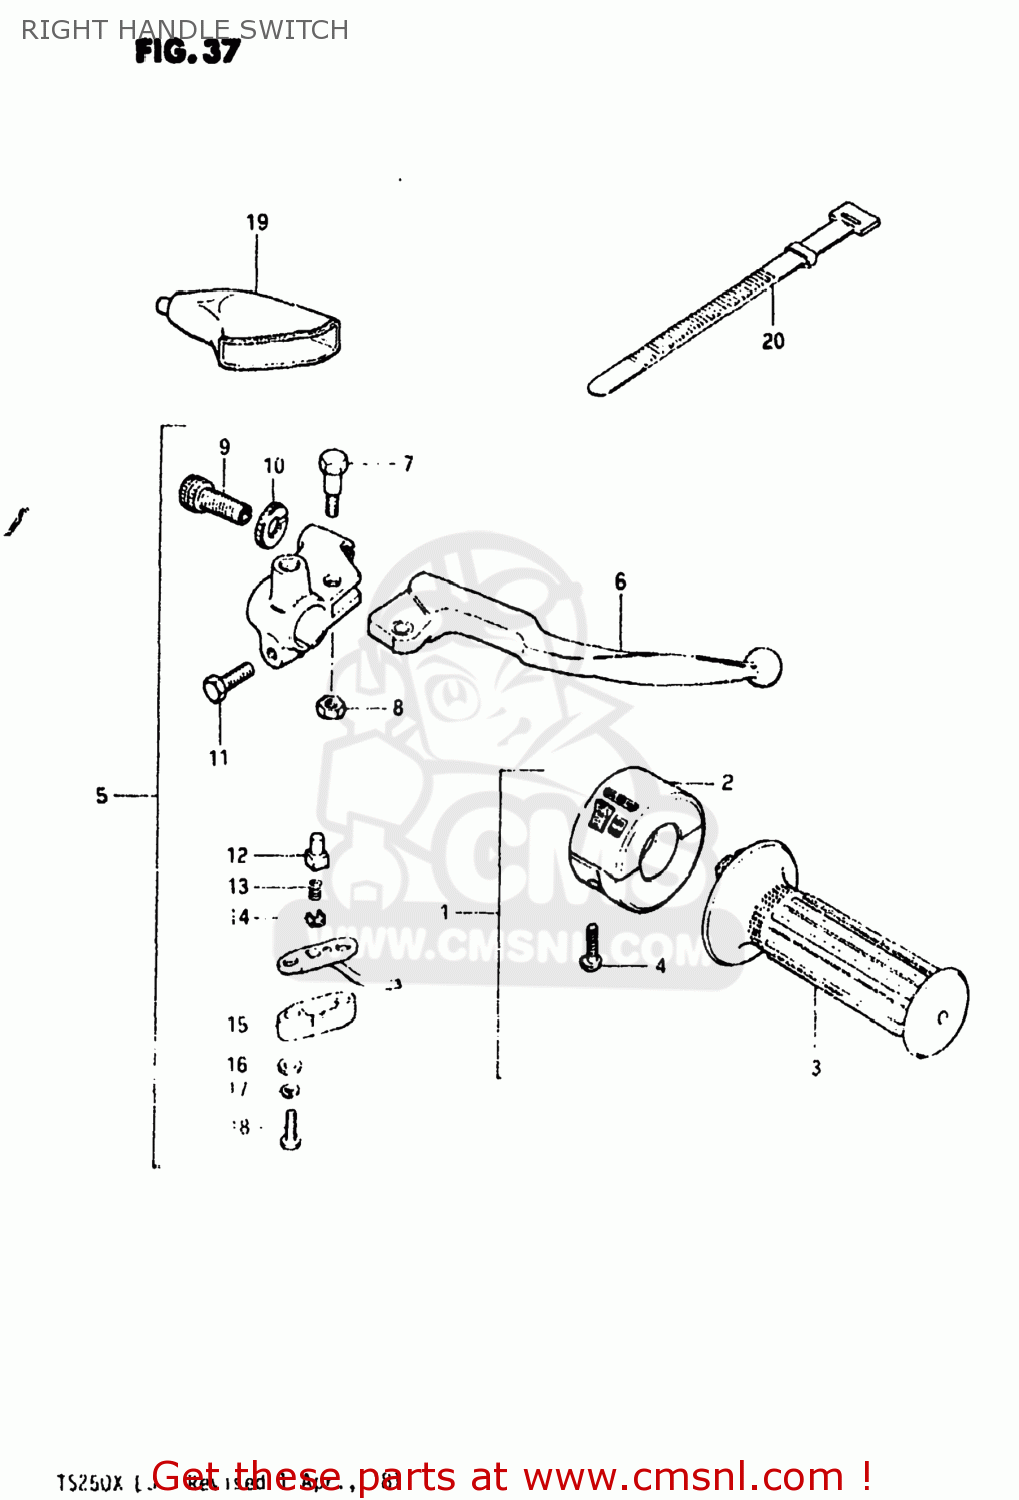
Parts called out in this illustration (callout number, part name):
1	CASE ASSEMBLY,THROTTLE
2	CASE ASSEMBLY,THROTTLE
3	GRIP,THROTTLE
4	SCREW
5	LEVER/SWITCH ASSEMBLY,BRAKE
6	LEVER,BRAKE
7	BOLT,LEVER
8	NUT 6MM
9	ADJUSTER,CABLE
10	NUT,CABLE ADJUSTER
11	BOLT
12	HOLDER
13	SPRING
14	PLATE
15	COVER,FR BK TERMINAL BASE
16	WASHER
17	LOCK WASHER
18	SCREW
19	COVER,CLUTCH LEVER
20	CLAMP(L:120)
